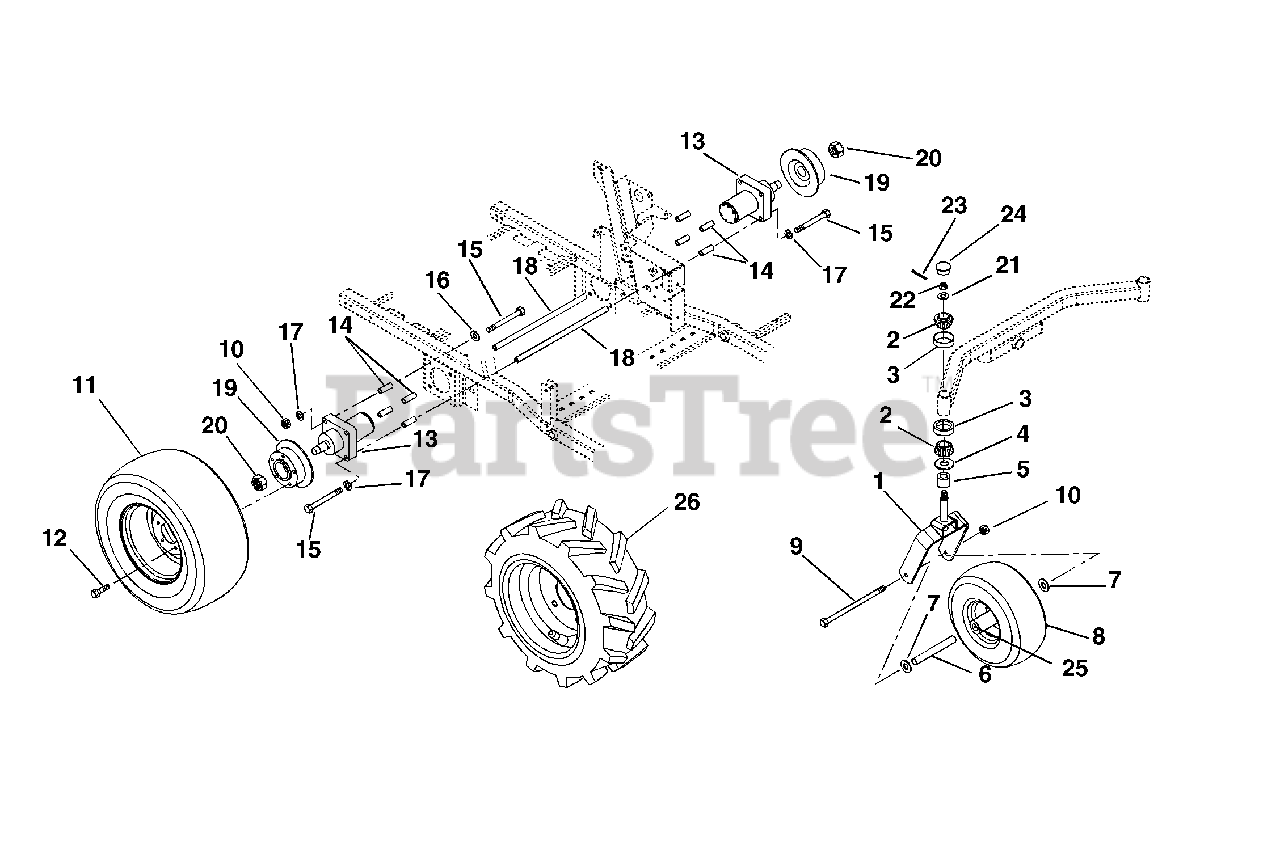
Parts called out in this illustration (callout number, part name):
1	Fork-Front
2	Bearing-Cone w/ Grease
3	Bearing-Cup 1.980 x .420
4	Bearing Seal 1.5 x 2 x .18
5	Spacer, PM, 1.03 I.D. x 1.5 O.D. x .375
6	Spacer-Wheel
7	Washer-Flat-Steel .515 x 1.625 x .250
8	Wheel/Tire Assembly
8	Tire, 15 x 6-6
9	Bolt-Hex .50-13 x 9.00 Grade 5
10	Nut-Locking-Center .50-13
11	Wheel-Tire 23 x 10.50 - 12 Multi-Trac
11	Wheel-Tire 23 x 8.50 Multi-Trac
11	Wheel-Tire Assembly 23 x 10 50-12
11	Tire 23 x 10.50
11	Tire 23 x 8.50-12 Multitrac C/S
12	Bolt-Lug .50-20 x 1.62
13	Hydraulic Wheel Motor
14	Bushing-Sleeve .513 x .748 x 2.129
15	Bolt-Hex .50-13 x 5.00 Grade 8
16	Spacer .500 x .750 x .321
17	Washer-Locking .50 x .125
18	Rod-Motor Connecting
19	Hub and Disc
20	Nut -Lock Jam Patch
21	Washer-Flat-Steel .755 x 1.375 x .062
22	Nut-Slotted .75-16
23	Pin-Cotter .16 x 1.00
24	Cap-Dust
25	Bearing, 25MM I.D. x 52MM OD x 15MM
26	Wheel/Tire Kit, 260Z L. & R.
26	Wheel/Tire-L.H. 23 x 10.5-12 Tru Power
26	Wheel/Tire-R.H. 23 x 10.5-12 Tru Power
26	Wheel/Tire 23 x 10.50 - 12 Tru Power
